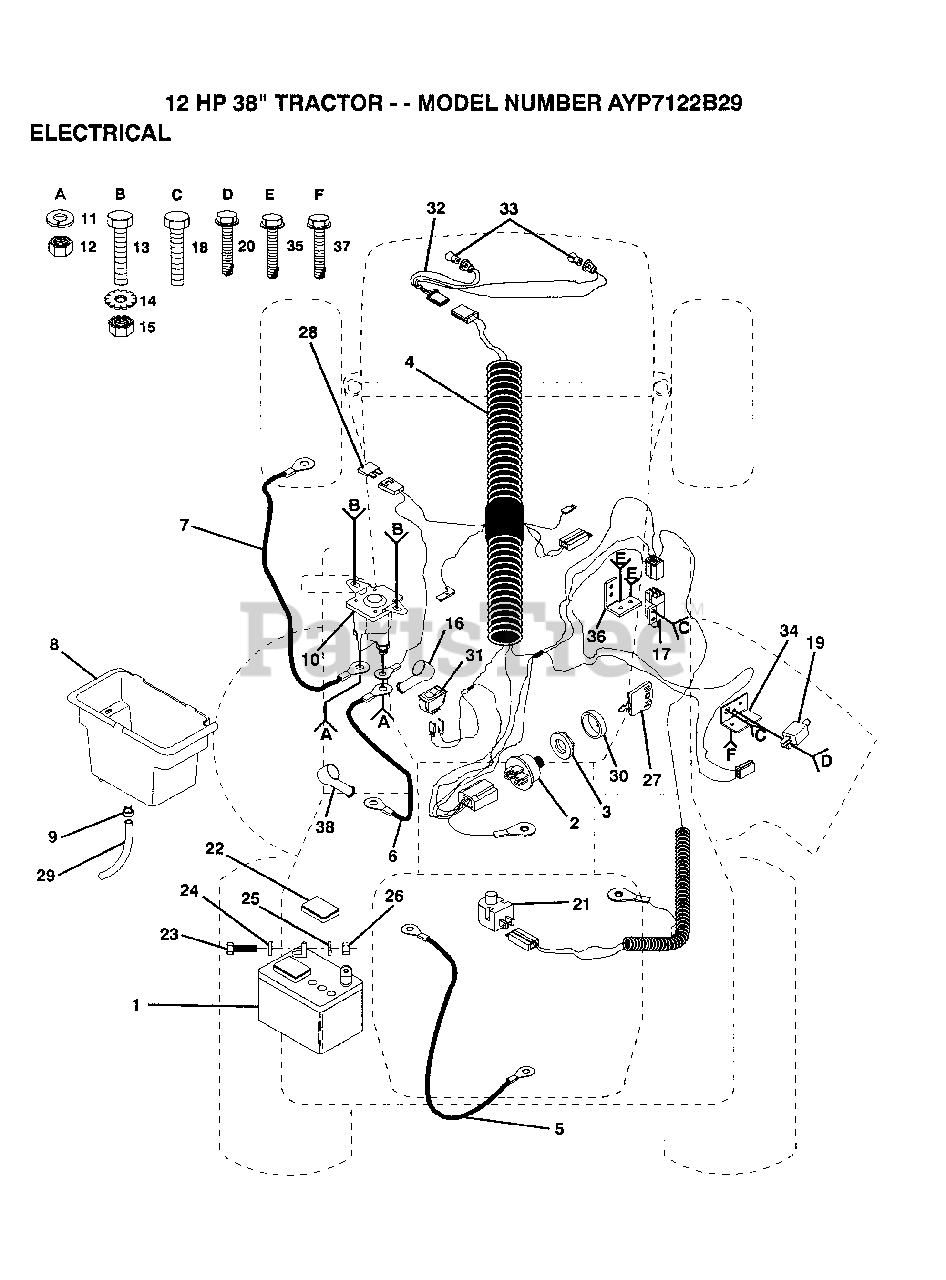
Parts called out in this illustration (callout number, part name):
3	NUT IGNITION
4	IGN HARNESS
5	CABLE T
7	"CABLE T, BATTERY"
8	BTRY CASE W/O LID
9	HOSE CLAMP T
12	NUT
13	BOLT
15	NUT
17	SWITCH INTERLOCKT
18	SCREW
19	SWITCH-INTER. GT
20	SCREW
21	SWITCH SEAT
22	"CAP,BATTERY "
23	BOLT LT
24	WASHER
25	LOCKWASHER
27	KEY
28	FUSE HYT
31	SWITCH LT
34	BRACKET LT
35	SCREW
36	SWITCH BRACKET
37	SCREW
